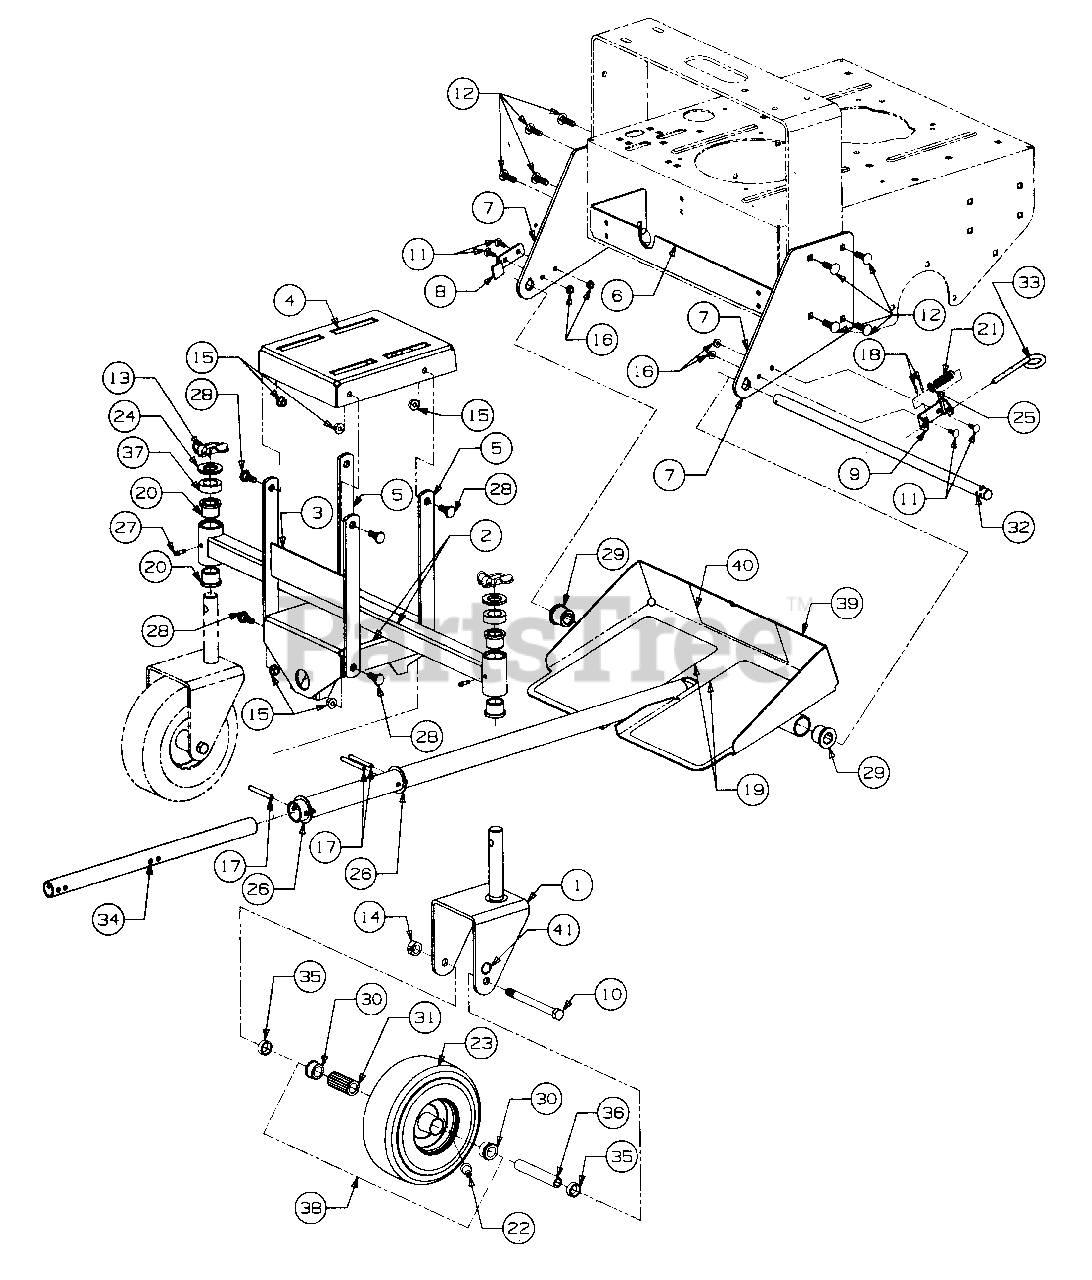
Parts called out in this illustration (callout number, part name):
2	Axle, Seat Sulky
3	Link Asy, Rear Parallel
5	Link, Parallel
6	Bracket, Engine Deck Support
7	Plate, Seat Sulky Mtg
8	Bracket, Pivot Pin Stop
9	Bracket, Locating Rod
10	Screw, Hex Cap, 1/2-20 X 5.50 Lg
11	Bolt, Carriage, 1/4-20 X .75 Lg
12	Bolt, Carriage, 3/8-16 X 1.25 Lg GR5
13	Pin, Klik
14	Nut, Hex Center Lock, 1/2-20
15	Nut, Hex Flanged, Lock, 3/8-16
16	Nut, Hex Flange Lock, 1/4-20
17	Pin, Spiral Spring, 5/16 Dia X 2.50 Lg Hd
18	Pin, Roll, 1/8 Dia X .63 Lg
19	Pad, Abrasive Foot
20	Bearing, Flange
21	Spring, Compression
22	Valve, Tubeless Air
23	Tire, Smooth, 9.0 X 3.50 X 4
24	Washer, Special
25	Washer, Flat, 5/16
26	Washer, Flat, 1.53 X 2.00 X .089 Thk
27	Fitting, Lube
28	Bolt, Shoulder, .50 Dia X .267 Lg
29	Bearing, Flange, .75 ID X 1.25 OD
30	Bearing, Graf Oil Flange
31	Bearing, Roller
32	Pin, Sulky Pivot
33	Rod, Pivot Pin Locating
34	Tube, Reinforcement
35	Spacer, .790 ID X .347 Lg
36	Spacer, Wheel
37	Spacer, 1.015 X 1.62 X .50 Lg
38	Wheel Assy, Caster
39	Tube, Footrest Pivot
40	Graphic, Riding Sulky Warning
41	Label, Inflation
